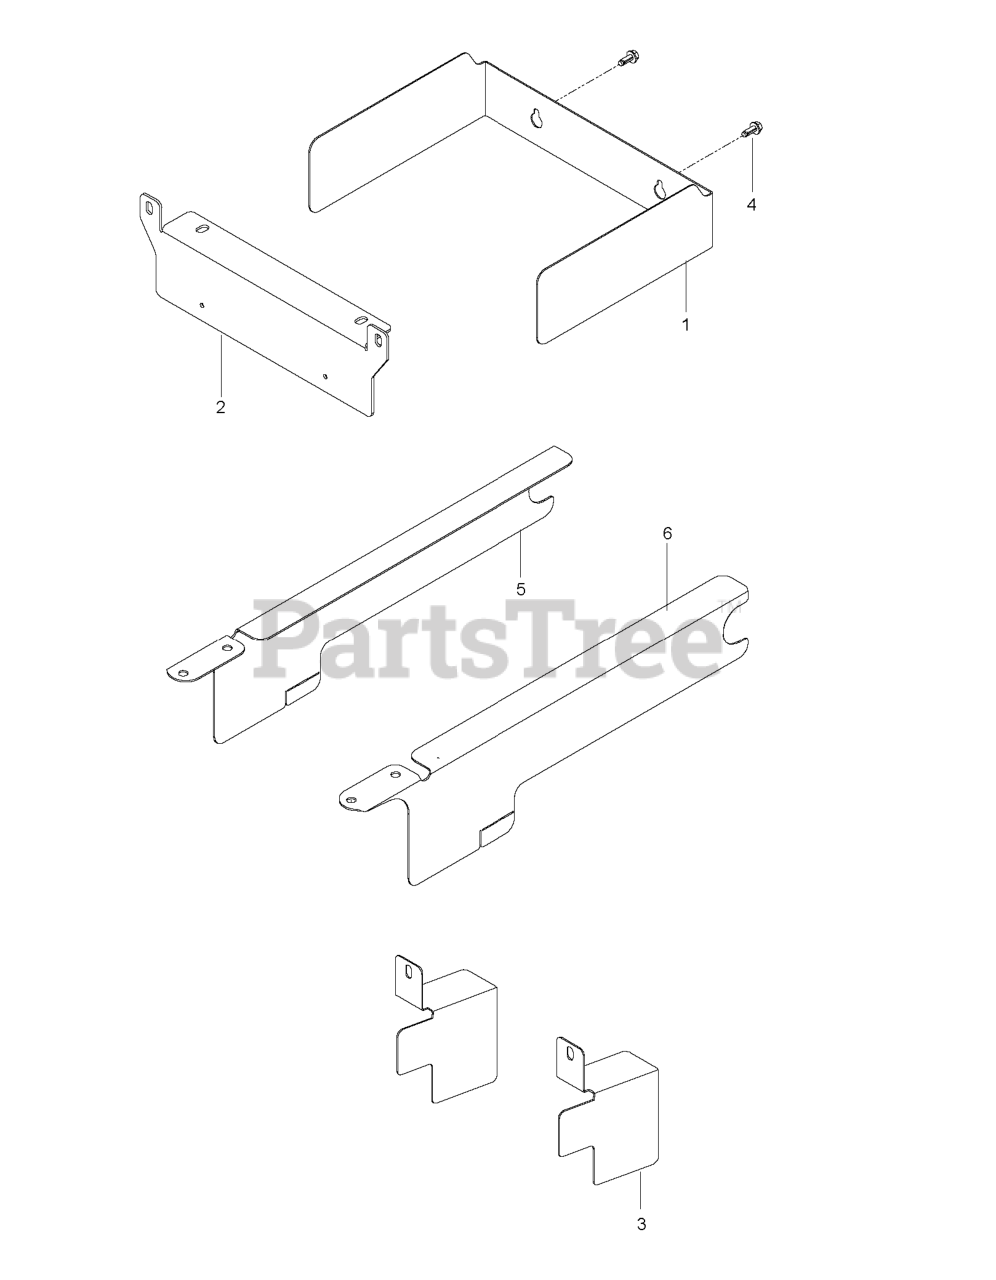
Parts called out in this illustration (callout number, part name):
1	BRACKET.GUARD.PZ.CLUTCH
2	GUARD.PZ.CLUTCH.BLK
3	GUARD.PZ.MIDSECTION.BL
4	SCREW- 1/4-20 X 5/8
5	SKIRT.RH.BLK
6	SKIRT.LH.BLK
